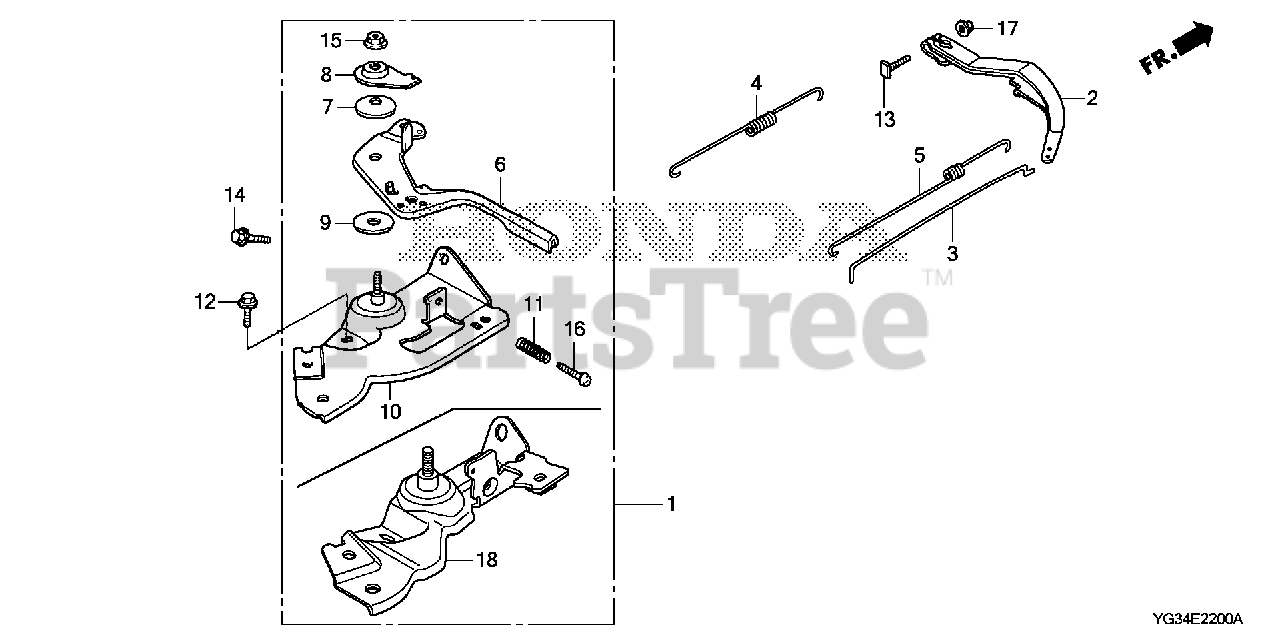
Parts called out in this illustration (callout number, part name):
1	CONTROL ASSY.
2	ARM, GOVERNOR
3	ROD, GOVERNOR
4	SPRING, GOVERNOR
5	SPRING, THROTTLE RETURN
6	LEVER, CONTROL
7	SPRING, LEVER
8	WASHER, CONTROL LEVER
9	SPACER, CONTROL LEVER
10	BASE, CONTROL
11	SPRING, CONTROL ADJUSTING
12	BOLT, FLANGE (6X12) (CT200)
13	BOLT, GOVERNOR ARM
14	BOLT, FLANGE (6X20) (CT200)
15	NUT, SELF-LOCK (6MM)
16	SCREW, PAN (5X25)
17	NUT, FLANGE (6MM)
